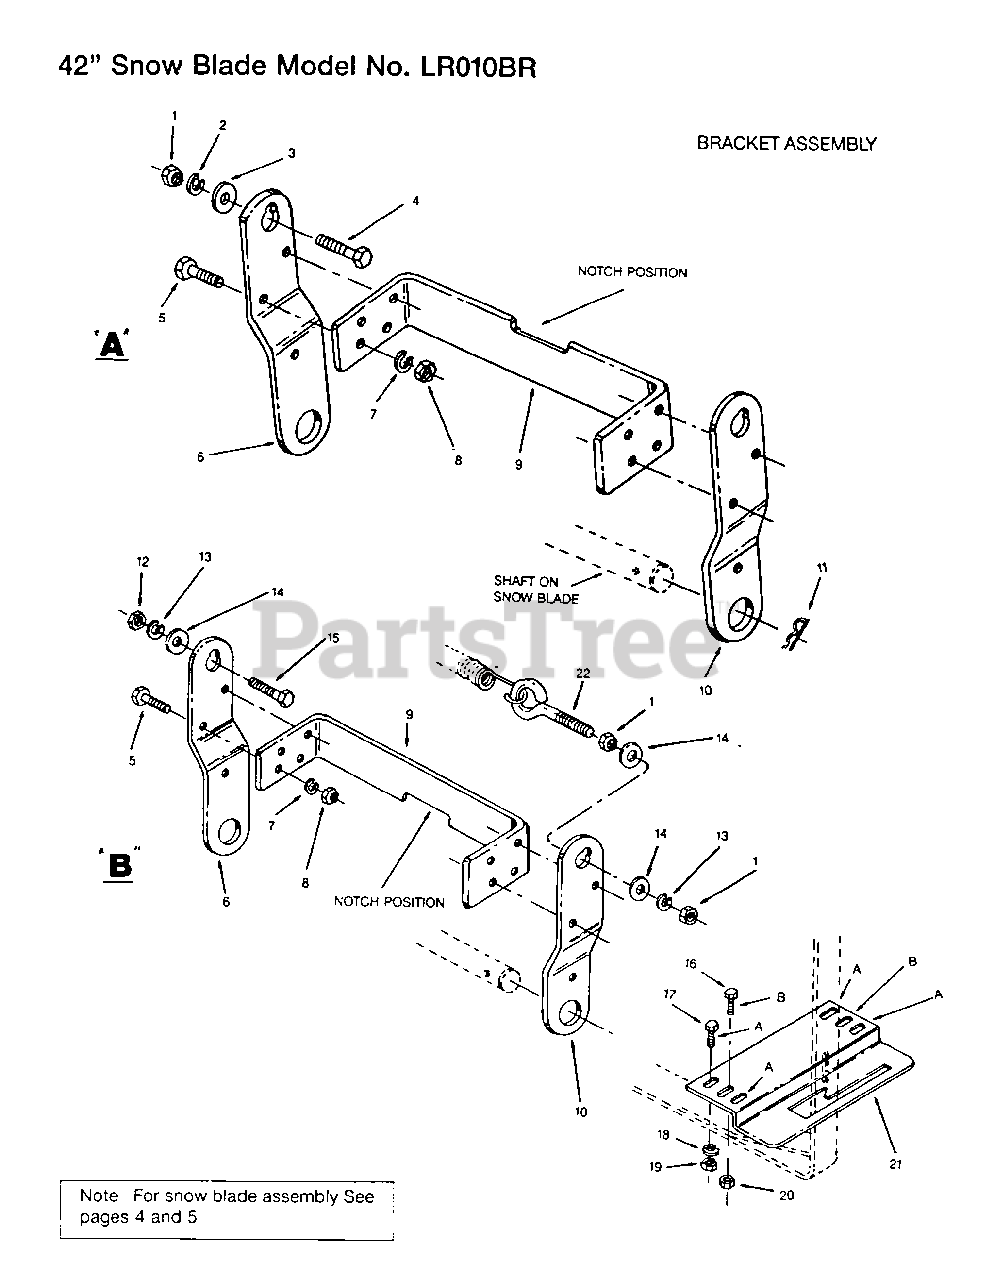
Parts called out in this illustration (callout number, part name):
6	MOUNTING BRKT
9	CROSS TIE BRKT
10	MOUNTING BRKT
11	HAIR PIN COTTER
21	LIFT LOCK PLATE
22	TOW HITCH - EYEBOLT
